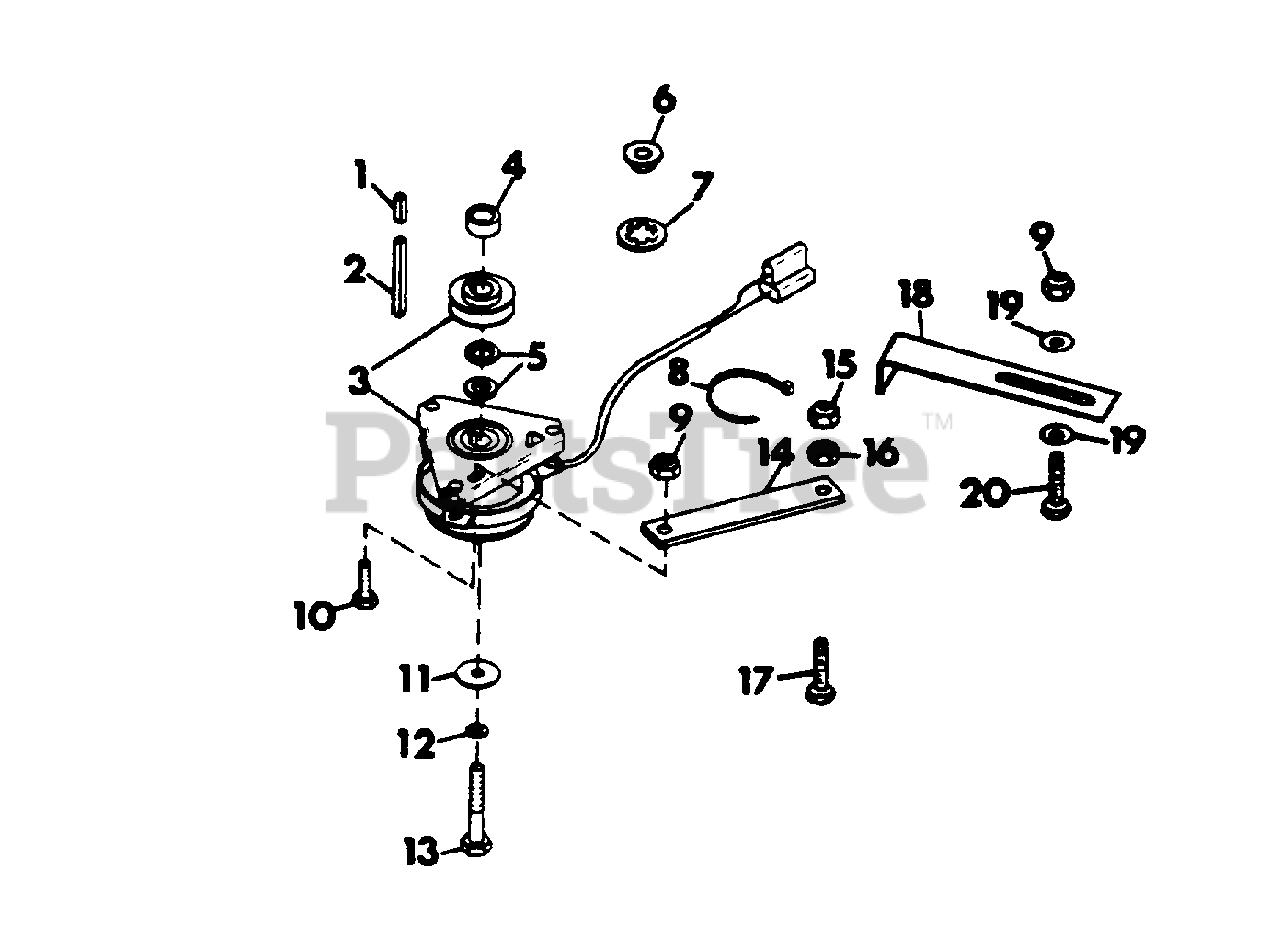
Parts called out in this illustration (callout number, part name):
1	KEY, SQUARE
2	KEY, RECTANGULAR
3	CLUTCH, ELECTRIC
4	SPACER, ELECTRIC CLUTCH
5	SPACER, ELECTRIC CLUTCH
6	BUSHING, NYLON
7	RING, RETAINING INT. TOOTH 1.000 SHAFT
8	TIE, CABLE
9	NUT, LOCK 5/16-18
10	BOLT, HEX 5/16-18X.75
11	WASHER, SPECIAL FLAT
12	WASHER, LOCK 7/16 REG.
13	BOLT, HEX 7/16-20X3.0
14	BRACE, PTO CLUTCH
15	NUT, LOCK 1/2-13
16	NUT, JAM 1/2-13 HEX
17	BOLT, HEX 1/2-13X2.75
18	GUIDE, V-BELT
19	WASHER, FLAT .344X.688X.065
20	BOLT, HEX 5/16-18X1.75
